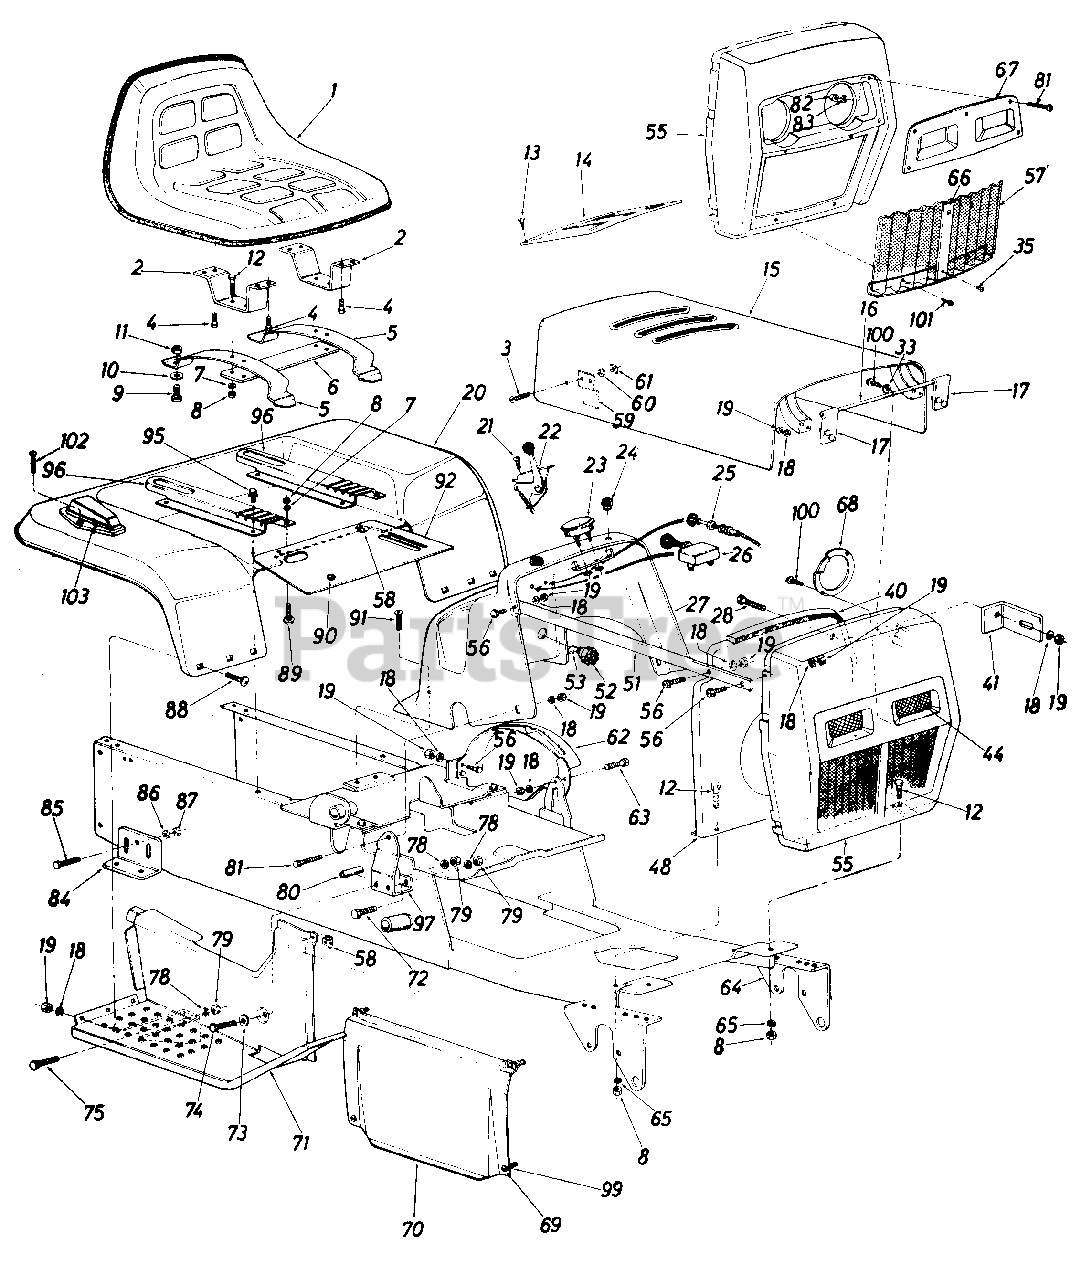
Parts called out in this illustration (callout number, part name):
1	Seat Ass'y. Comp
2	Seat Support Brkt.
3	Truss Hd. Mach. Scr. #10-24 x.38" Lg.
4	Hex Wash. Hd. Self-Tap Scr. 3/8-16 x .75" Lg.
5	Seat Spring
6	Seat Support Plate
7	L-Wash. 5/16" Scr.*
8	Hex Nut 5/16-18 Thd.*
9	Nylon Scr. 1/2-13 x 75" Lg.
10	Fl-Wash .531 I.D. x .930 O.D.
11	Hex Cent. L-Nut l/2-13 Thd.
12	Hex Scr. 5/16-18 x .75" Lg.*
13	Self-Tap Oval Hd. Scr. 1/2" Lg.
14	Dash Panel Cover
15	Hood Ass'y.
16	Hinge Rod
17	Hood Hinge Ass'y.
18	L-Wash. 1/4" Scr.*
19	Hex Nut 1/4-20 Thd.
20	Rear Fender
21	Fl-Hd. Truss Scr. #10 x .62" Lg.
22	Throttle Control
23	Ammeter
24	Rubber Bumper
25	Choke Control
26	Light Switch
27	Dash Panel
28	Hex Scr. 1/4-20 x .62" Lg.*
28	Hood Support Brkt Ass'y. R. H .
33	Fl-Wash. .250 I.D. x 1.25 O.D.
35	Hex Scr. 1/4-20 x .38" Lg.*
40	Foam Strip
41	Heat Shield Brkt.
44	Head Lamp
48	Heat Shield
48	Truss Mach. Scr. 1/4-20 x .75" Lg.*
51	Grille Strap
52	Ignition Switch
53	Ignition Key
55	Grille
56	Hex Scr. 1/4-20 x .75" Lg.*
57	Grille Screen
58	Clip-On Receptacle
59	Hood Spring
60	L-Wash. #10
61	Hex Nut #10-24
62	Speed Control Guide
63	Truss Mach. Scr. 1/4-20 x .75" Lg.*
64	Frame Ass'y.
65	Bell-Wash. 5/16" Scr.*
66	Moulding
67	Headlight Bezel
68	Headlight Retainer
69	1/4-Turn Stud
70	Hood Lower Side Panel
71	Foot Step Panel Ass'y. R.H.
71	Foot Step Panel Ass'y. L.H.
72	Hex Scr. 3/8-16 x 1.00" Lg. Grade 5
73	Fl-Wash. .385 I.D. x .62 O.D.
74	Hex Scr. 3/8-16 x 3.00" Lg.*
75	Hex Scr. 3/8-16 x 1.00" Lg. Grade 5
78	L-Wash. 3/8" Scr.*
79	Hex Nut 3/8-16 Thd.
80	Spacer .375 I.D. x .62 O.D. x 2.00" Lg.
81	Truss Mach. Scr. #10-24 x 1.0" Lg.
82	Sq. Nut #10-24 Thd.
83	Ext. L-Wash. #10 I.D.
84	Transaxle Support Brkt.
85	Rd. Hd. Rib Neck Scr. 3/8-24
86	L-Wash. 3/8" Scr.*
87	Hex Nut 3/8-24 Thd.*
88	Carr. Bolt 1/4-20 x .50" Lg.*
89	Carr. Bolt 5/16-18 x .62" Lg.*
90	Snap Bushing
91	Fl-Hd. Self-Tap Scr. 1/4-20 x .62" Lg.
96	Seat Adjustment Brkt.
100	Thread Rolling Scr. 1/4"
101	Drive Scr. #7
102	Fl. C-Sunk AB-Tap Scr. #10 x 1.0" Lg.
103	Tail light
